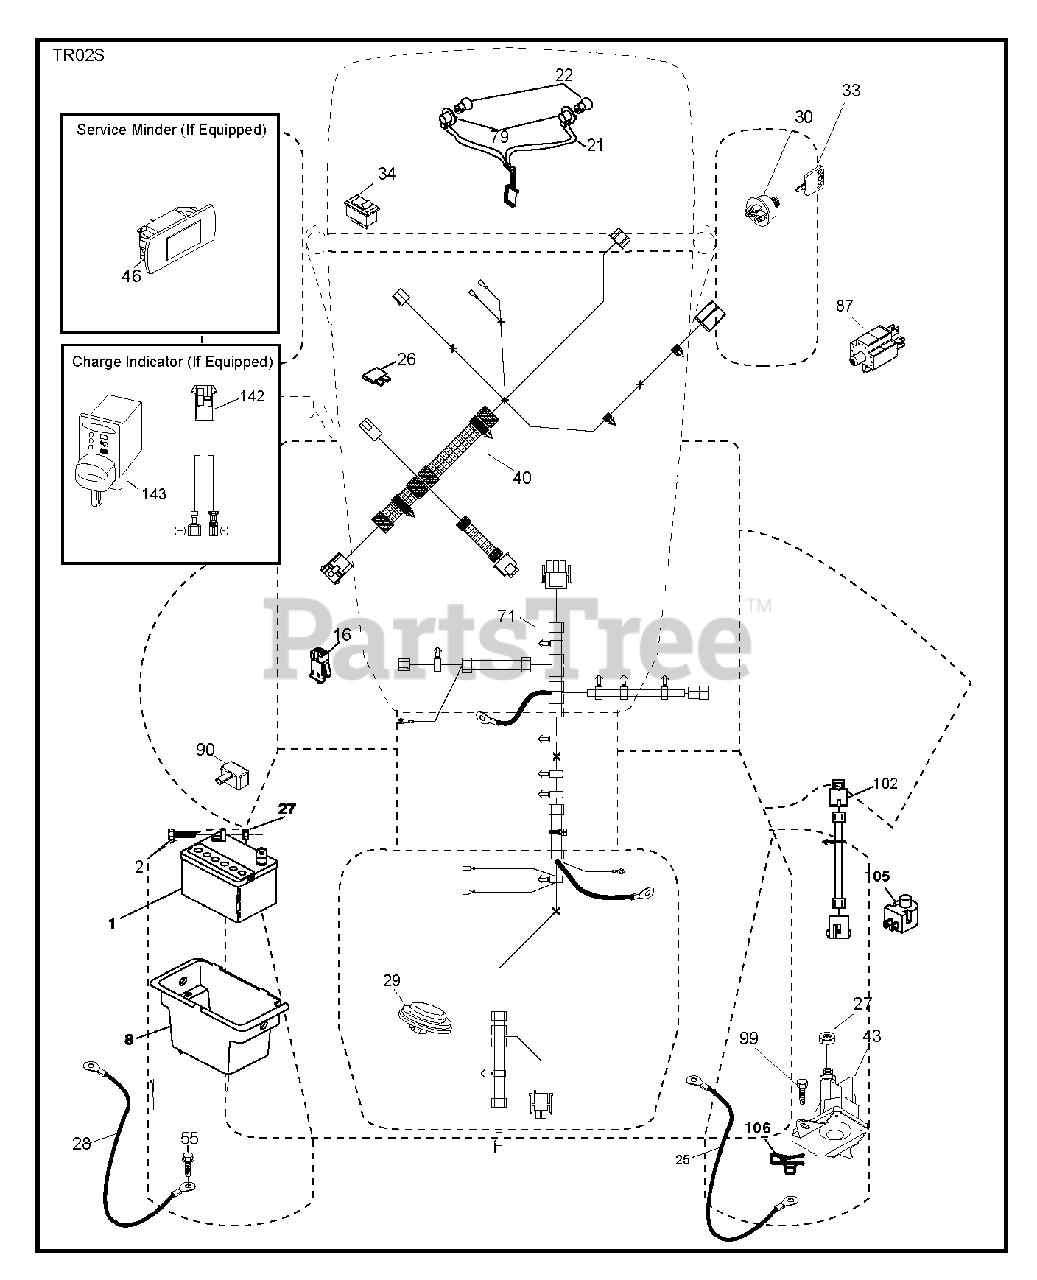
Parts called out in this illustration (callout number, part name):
1	REPL BY 532 12 38-99
2	BOLT.HEX.1/4.X.3/4.DICHROMATE
8	BOX.BATTERY.MNT.REAR.L
16	SWITCH INTERLOOK PUSH-IN
21	HARNESS.LIGHT W/4152J BULBS
22	LIGHTBULB
25	CABLE.BATT.RED.8GA.17
26	FUSE 20AMP
27	NUT
28	CABLE.GROUND.REAR.BATTERY.8G
29	SWITCH.SEAT.DELTA.OPC.
30	SWITCH.IGN.DELTA.W.LGH.ROS
33	KEY.CHAIN.BLISTER.PACK.GEN.USA
34	SWITCH LT
40	Dash Harness, cc.Rrbatt.Rdystrt
43	SOLENOID.W/BRASS.PLUNGER
55	SCREW 5/16"
71	HARNESS.CHASSIS.RRBATT.RDYSTRT
79	BULB HOLDER ASM.
87	SWITCH.INTRLCK.CLUTCH.
90	COVER.TERMINAL.BATTERY
99	SCREW HEXWSHR 1/4-20X3/4
102	HARNESS.PIGTAIL.VARIATOR.SD
105	REVERSE SWITCH
106	1/4-20 U NUT
